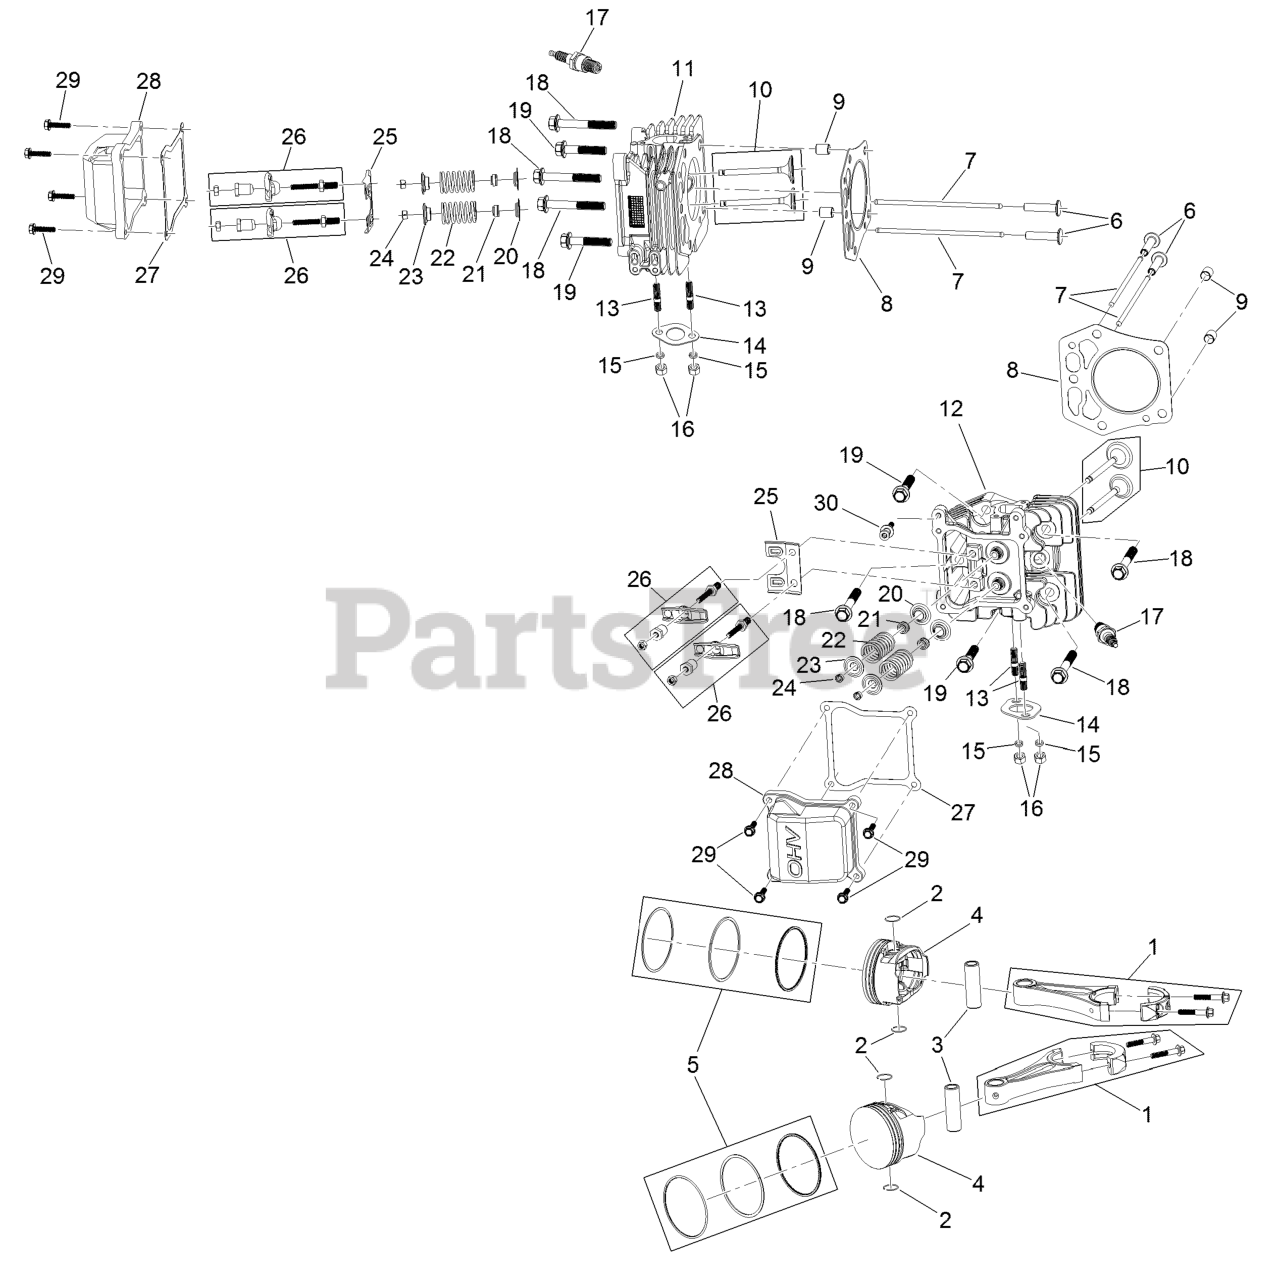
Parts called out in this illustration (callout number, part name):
1	CONNECTING ROD ASM
2	CLIP-PIN, PISTON
3	PIN-PISTON
5	PISTON RING SET
6	LIFTER-VALVE
7	ROD-PUSH
8	GASKET-HEAD, CYLINDER
9	PIN-DOWEL
10	VALVE SET
11	HEAD-CYLINDER
12	HEAD-CYLINDER
14	GASKET-EXHAUST
15	WASHER-LOCK, SPLIT
17	SPARK PLUG
18	SCREW-HWH
19	SCREW-HWH
20	SEAT-SPRING, VALVE
21	SEAL-STEM, VALVE
22	SPRING-VALVE
23	RETAINER-SPRING, VALVE
24	KEEPER-VALVE
25	PLATE-GUIDE, PUSH ROD
27	GASKET-VALVE COVER
28	COVER-VALVE
29	SCREW-HHF
30	SCREW-SHOULDER, HH
